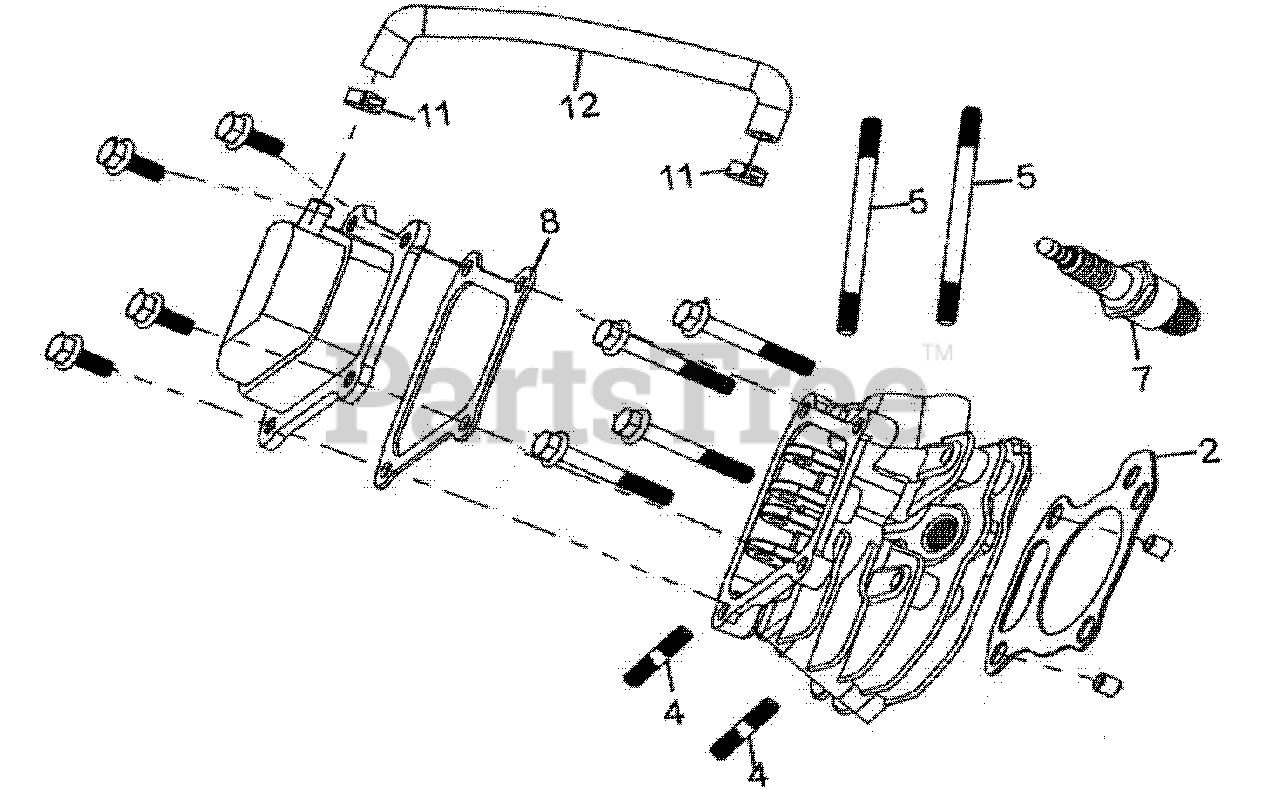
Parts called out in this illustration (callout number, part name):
2	GASKET,CYLINDER
4	BOLT ,STUD ,EXHAUST
5	BOLT ,STUD ,IN
7	SPARK PLUG E6TC
8	PACKING , HEAD COVER
11	LOOP, TUBE
12	TUBE, BREATHER
